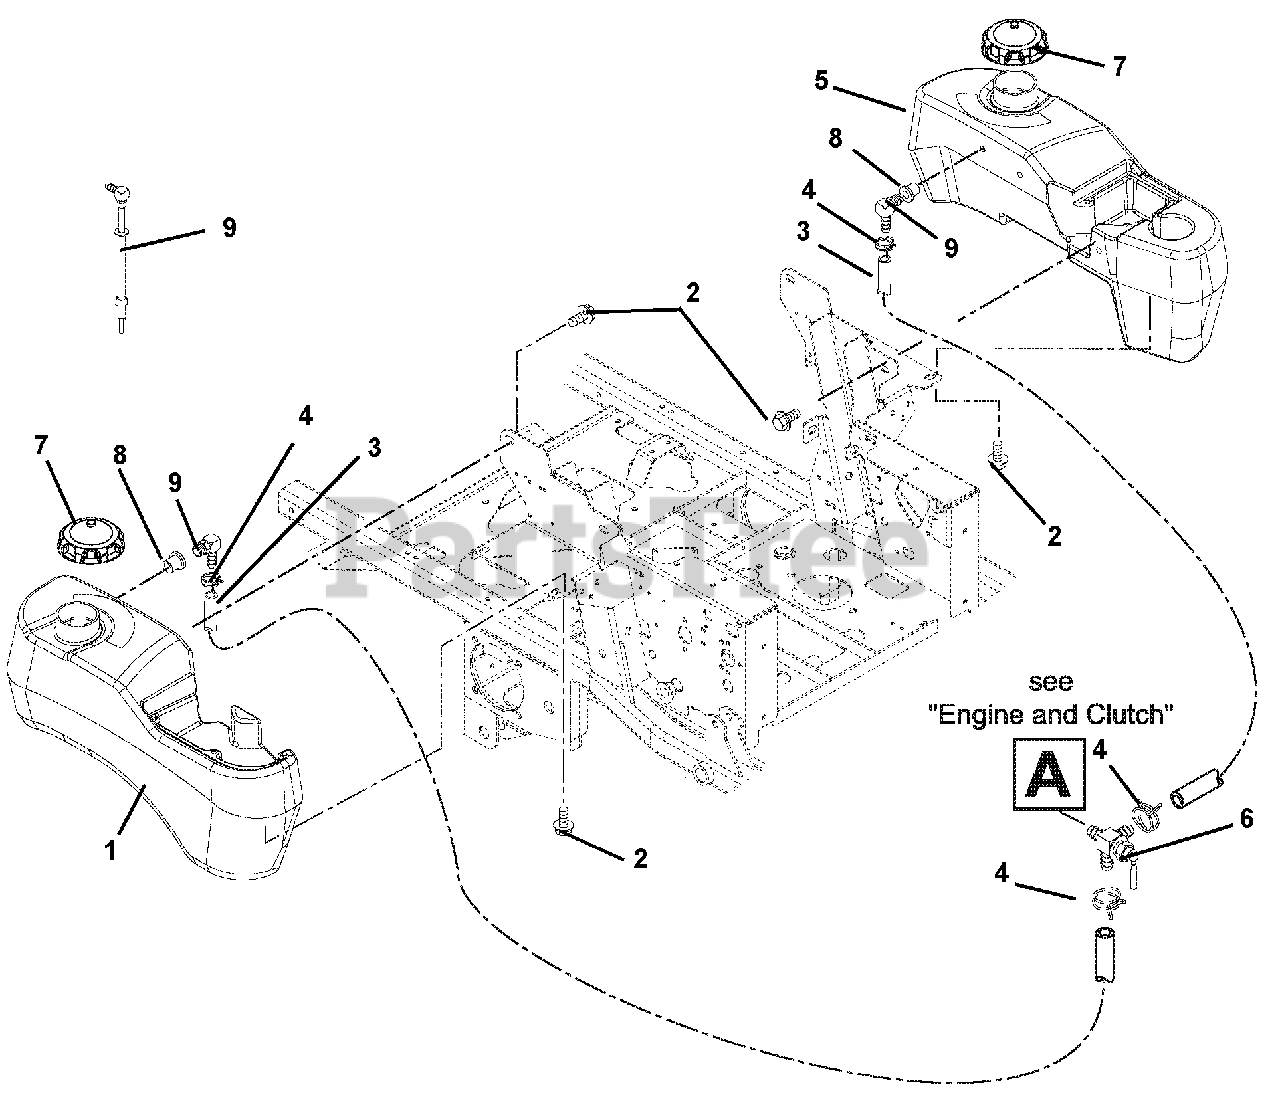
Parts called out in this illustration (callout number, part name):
1	Tank, Fuel - Right Hand
2	Bolt, SEMS .31-18 x .62
3	Hose, .25 Low-PERM Bulk Gas (2 @ 42 in.)
4	Clamp, Fuel Line
5	Tank, Left Hand Fuel
6	Valve, Fuel
7	Cap, Gas
9	Assembly, Large Tank Fuel Pick-up
